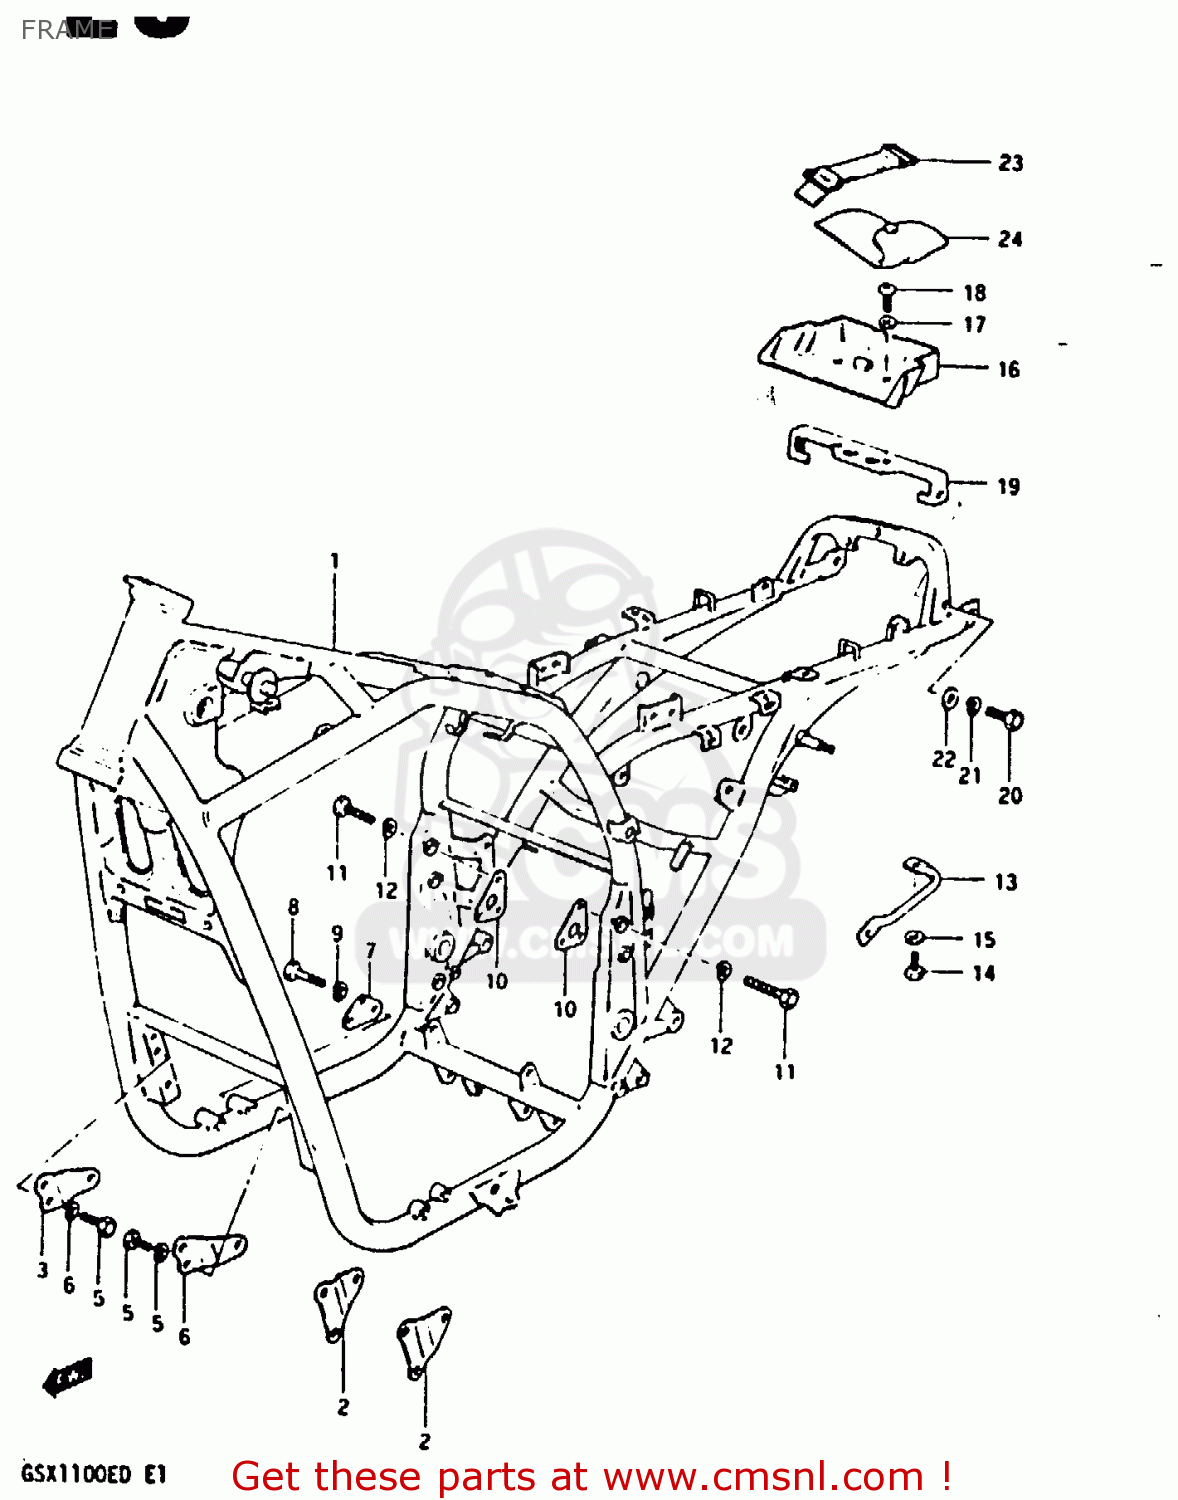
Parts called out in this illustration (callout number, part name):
1	FRAME
2	PLATE,ENGINE MOUNTING
3	PLATE,ENGINE MOUNTING NO
4	PLATE,ENGINE MOUNTING NO
5	BOLT
6	LOCK WASHER
7	PLATE,ENGINE MOUNTING
8	BOLT
9	LOCK WASHER
10	PLATE,ENGINE MOUNTING
11	BOLT
12	LOCK WASHER
13	GRIP,FRAME HANDLE
14	BOLT
15	WASHER
16	HOLDER,TOOL
17	WASHER(6.5X30X1.6)
18	SCREW
19	PLATE,TOOL HOLDER
20	BOLT
21	LOCK WASHER
22	WASHER
23	BAND
24	TOOL ASSY
